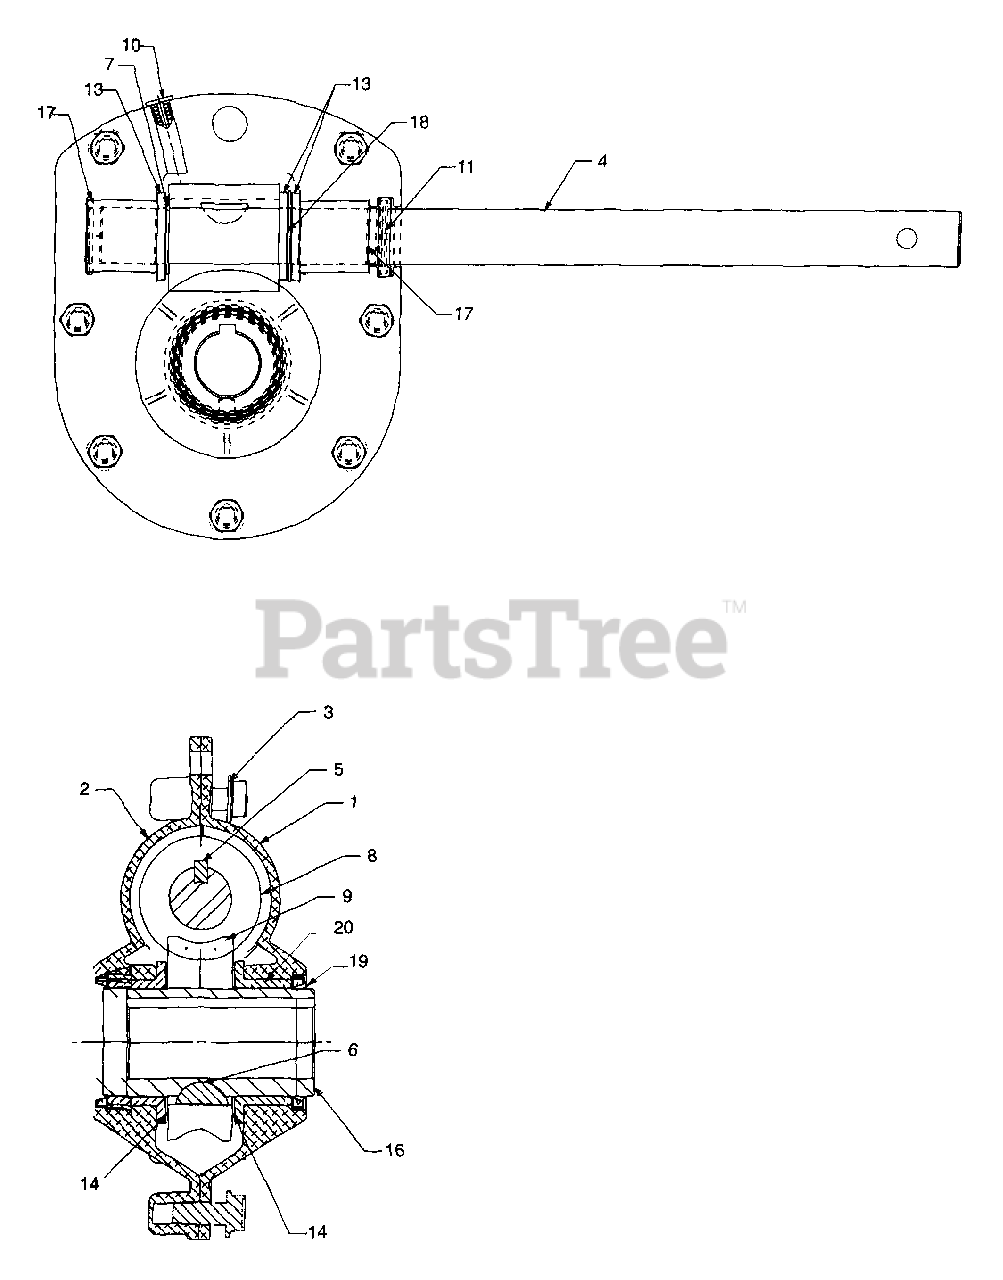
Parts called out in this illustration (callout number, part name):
1	Auger Housing Ass'y, L.H.
2	Auger Housing Ass'y, R.H.
3	Scr. TT HxWash. 5/16-18:.75" Lg.
4	Auger Input Shaft
5	Key, Hi Pro 3/16 x 3/4 Dia.
6	Key, Woodruff #91:1/4 x 3/4
7	Retaining Ring
8	Worm Gear Double Thread LH
9	Worm Gear LH
11	Oil Seal
13	Wash. Flat .88 I.D. x 1.380 O.D. x .125
14	Wash. Fl. 1.52 I.D. x 2.0 O.D. x .30
16	Worm Gear Shaft
17	Sleeve
18	Thrust Bearing
19	Oil Seal
20	Flange Bearing
